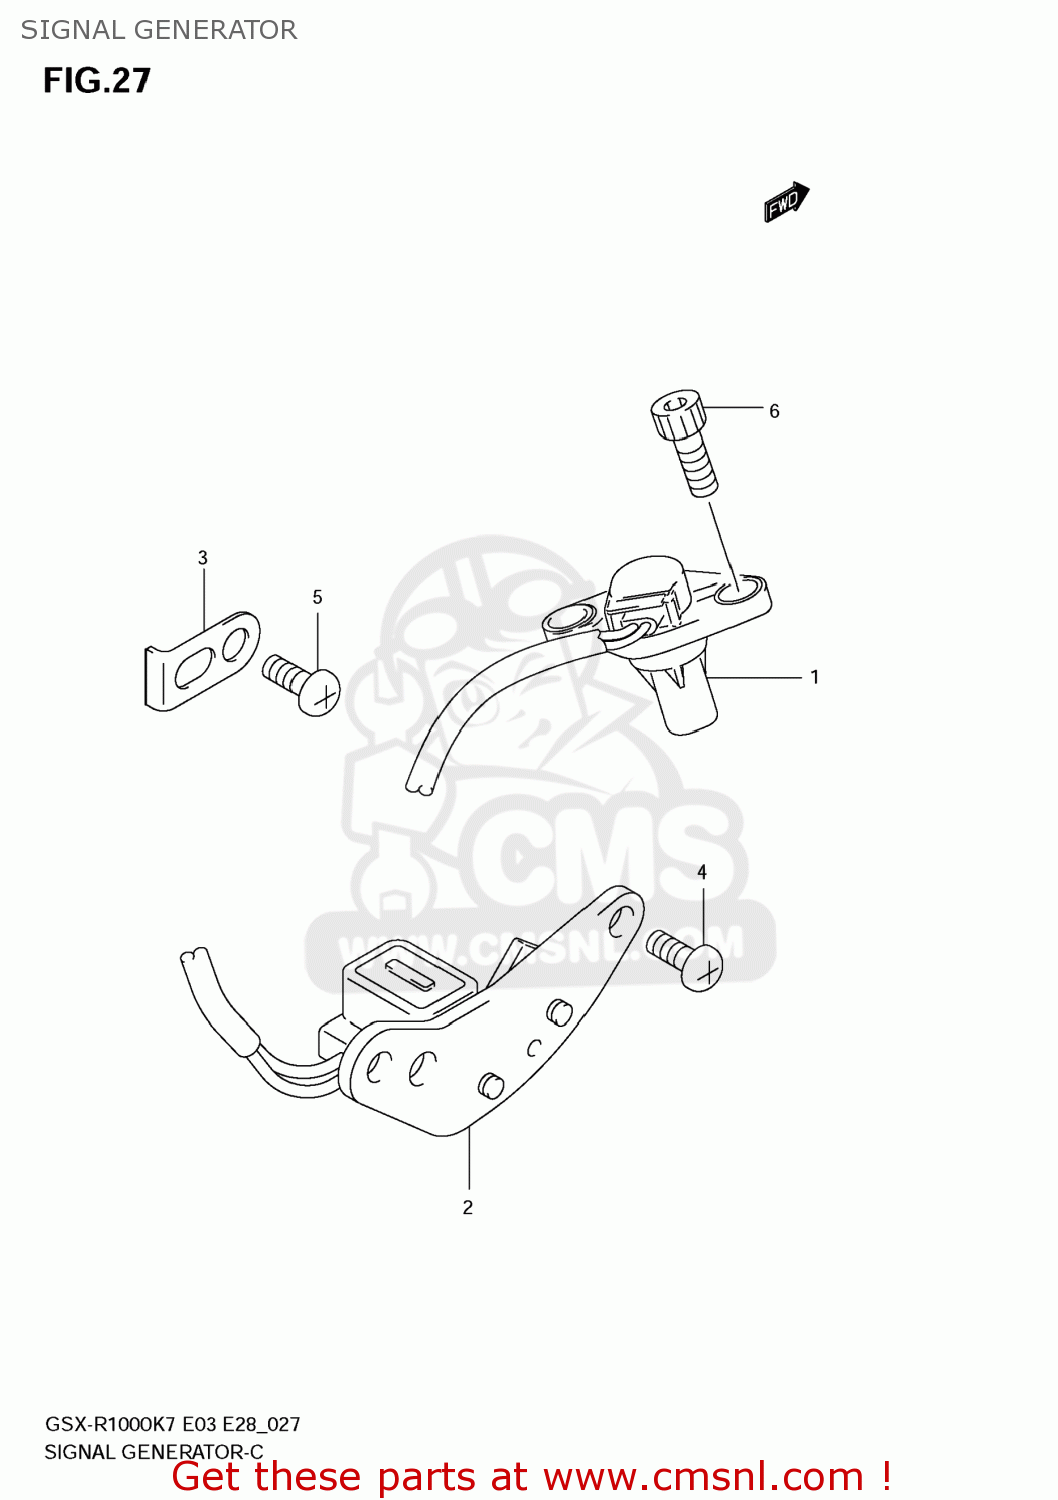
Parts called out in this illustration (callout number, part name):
1	SENSOR ASSY,CAM POSITION
2	STARTER SIGNAL GENERATOR
3	CLAMP,SIGNAL GENERATORERATOR
4	SCREW
5	SCREW
6	BOLT
